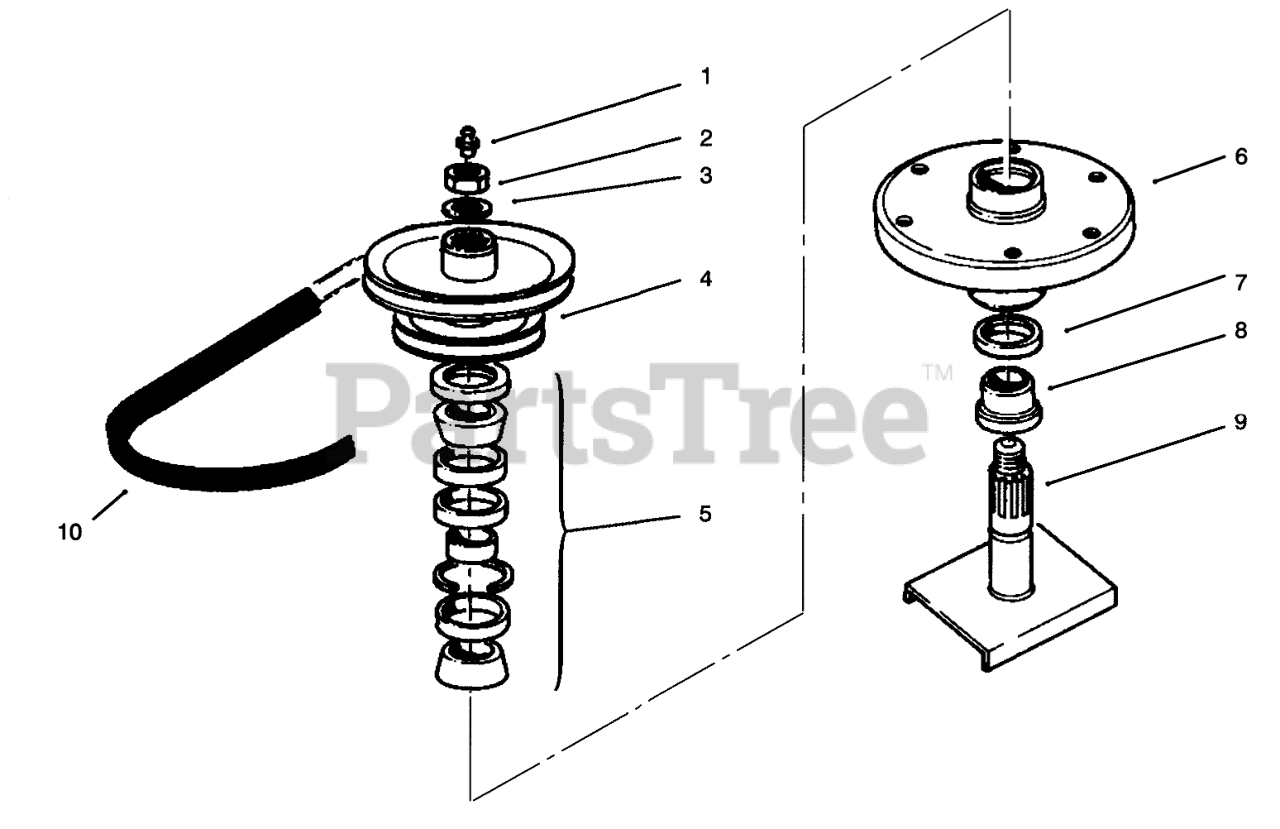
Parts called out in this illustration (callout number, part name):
1	FITTING-GREASE
2	NUT-HEX
3	WASHER
4	PULLEY AND HUB ASM
5	BEARING ASM
6	HOUSING-SPINDLE
7	SEAL-OIL
8	SPACER
9	Shaft-Spindle
10	V-BELT
